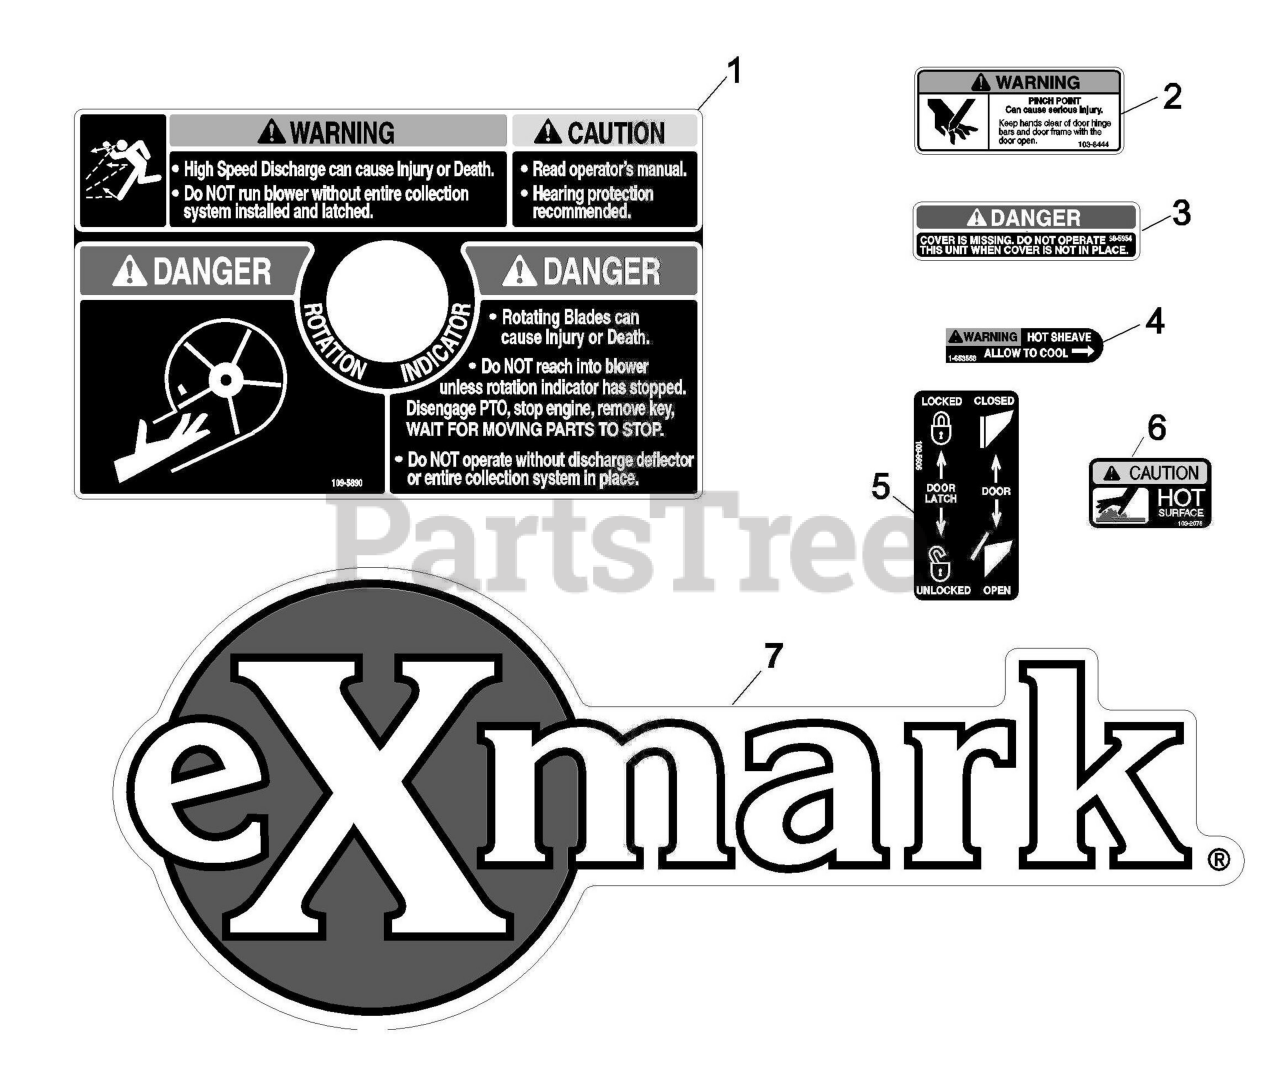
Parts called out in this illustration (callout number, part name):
1	DECAL-WARNING, BLOWER
2	DECAL-PINCH POINT
3	DECAL-COVER, MISSING
4	DECAL-WARNING
5	DECAL,FRUVD DOOR OPERATIO
6	DECAL-CAUTION
7	DECAL,EXMARK LOGO
